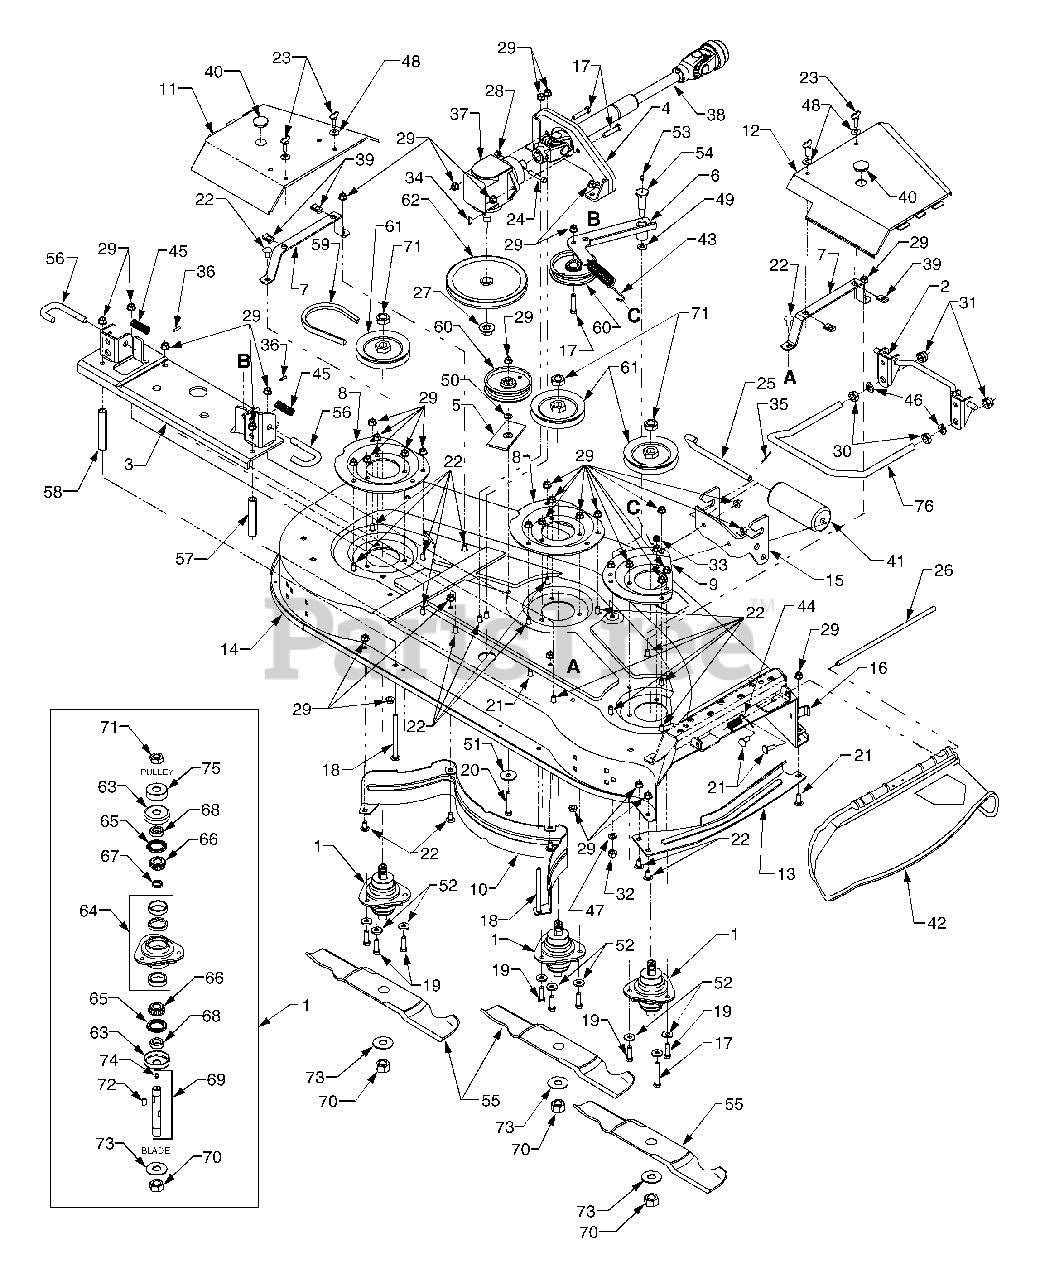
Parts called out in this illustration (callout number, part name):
1	Assembly, Spindle
3	Bracket, Gearbox
4	Bracket, Drive
6	Bracket, Idler
8	Disk, Reinforcement (Ctr., L.H.)
9	Disk, Reinforcement (R.H.)
11	Cover, Belt (L.H.)
12	Cover, Belt (R.H.)
13	Guard, Finger
15	Bracket, Roller Front
16	Stop, Chute Deflector
17	Screw, Hex Cap 3/8-16 x 1.75 GR5
18	Carriage, Bolt 3/8-16 x 5.0 GR5
19	Screw, Hex Cap 3/8-16 x 1.25 GR5
20	Screw, Hex Cap 3/8-16 x 2.25 GR5
21	Carriage, Bolt 3/8-16 x 1.0
22	Carriage, Bolt 3/8-16 x .75
23	Screw, Thumb Adjust 5/16-18x1
24	Screw, Sock. Hd. 5/16-18 x 1.75
25	Pin, Roller 1/2 x 7.31
26	Pin, Hinged 375 x 12.55
27	Nut, Hex Flanged 5/8-18
28	Nut, Hex Lock 5/16-18
29	Nut, Flange Lock 3/8-16
30	Nut, Hex Jam 5/8-11
31	Nut, Hex Lock 5/8-11
32	Nut, Hex 7/16-14
33	Nut, Hex Top Lock Jam, 3/8-16
34	Key, Hi-Pro
35	Pin, Cotter 3/32 x 1.25
36	Pin, Spirol
37	Drive, Right Angle
38	Shaft, Drive
39	Nut, "U" 5/16-18
40	Plug, Button
41	Roller, Front
42	Deflector, Chute
43	Spring, Extension 6.5" Lg
44	Spring, Torsion
45	Spring, Compression
46	Washer, Lock 5/8" I.D.
47	Washer, Lock 7/16" I.D.
48	Washer, Bell .34" I.D.
49	Washer, Flat .47" I.D. x .88" O.D.
50	Washer, Flat .47" I.D. x .75" O.D.
51	Washer, Flat .406" I.D.
52	Washer, Flat .406" I.D.
53	Fitting, Grease
54	Bolt, Shoulder .68" Dia. x 1.59
55	Blade, High Lift 18.5" Lg.
56	Pin, Mower Support
57	Spacer, .405" I.D. x 3.875" Lg.
58	Spacer, .405" I.D. x 4.075" Lg.
59	Belt, "V" .117" Lg
60	Pulley, Flat
61	Pulley, "V"
62	Pulley, Drive
63	Cup, Spindle
64	Housing w/ Cups, Spindle
65	Seal, Oil
66	Cone, Bearing
67	Spacer, Bearing
68	Spacer .755" I.D. x 1.25" O.D.
69	Kit, Shaft w/Seal
70	Nut, Hex 3/4-16 GR8
71	Nut, Hex Jam, 3/4-16 GR5
72	Key, #91 Woodruff
73	Washer, Flat .781" I.D. x 2" O.D.
74	Fitting, Grease
75	Spacer
76	Rod, Front Lift
